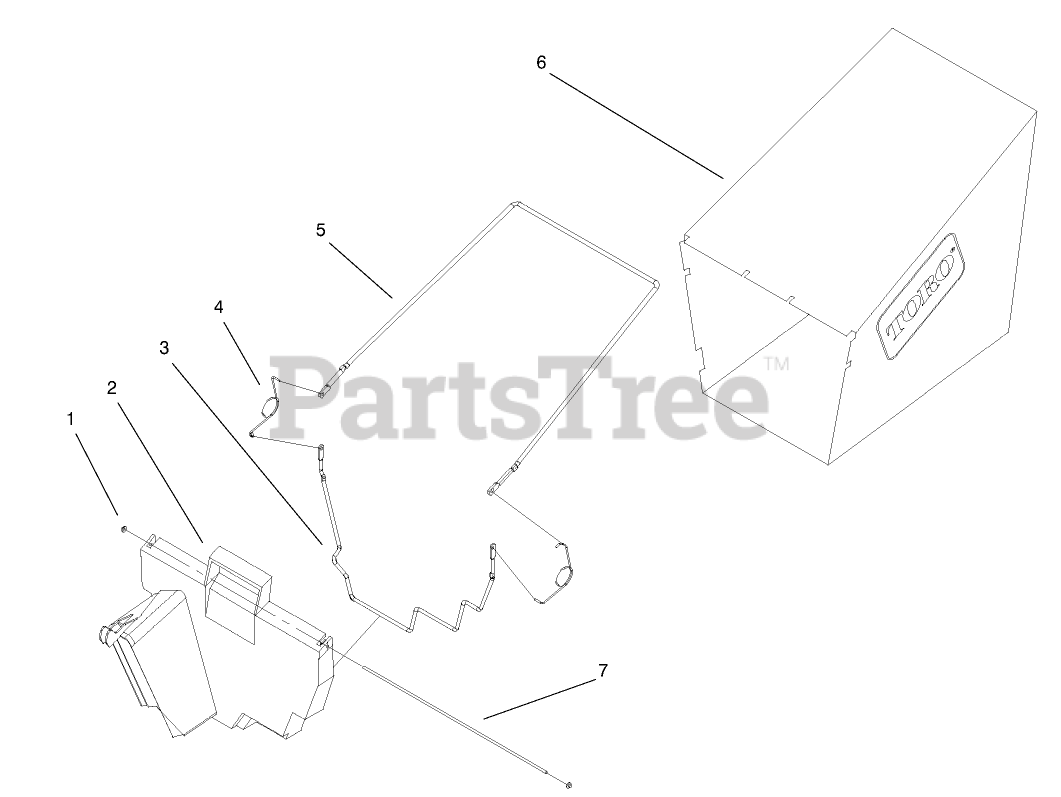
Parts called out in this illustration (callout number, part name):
1	NUT-PUSH
2	DOOR-BAG
3	FRAME-BAG
4	SPRING
6	BAG-GRASS
7	HINGE-DOOR, BAG
